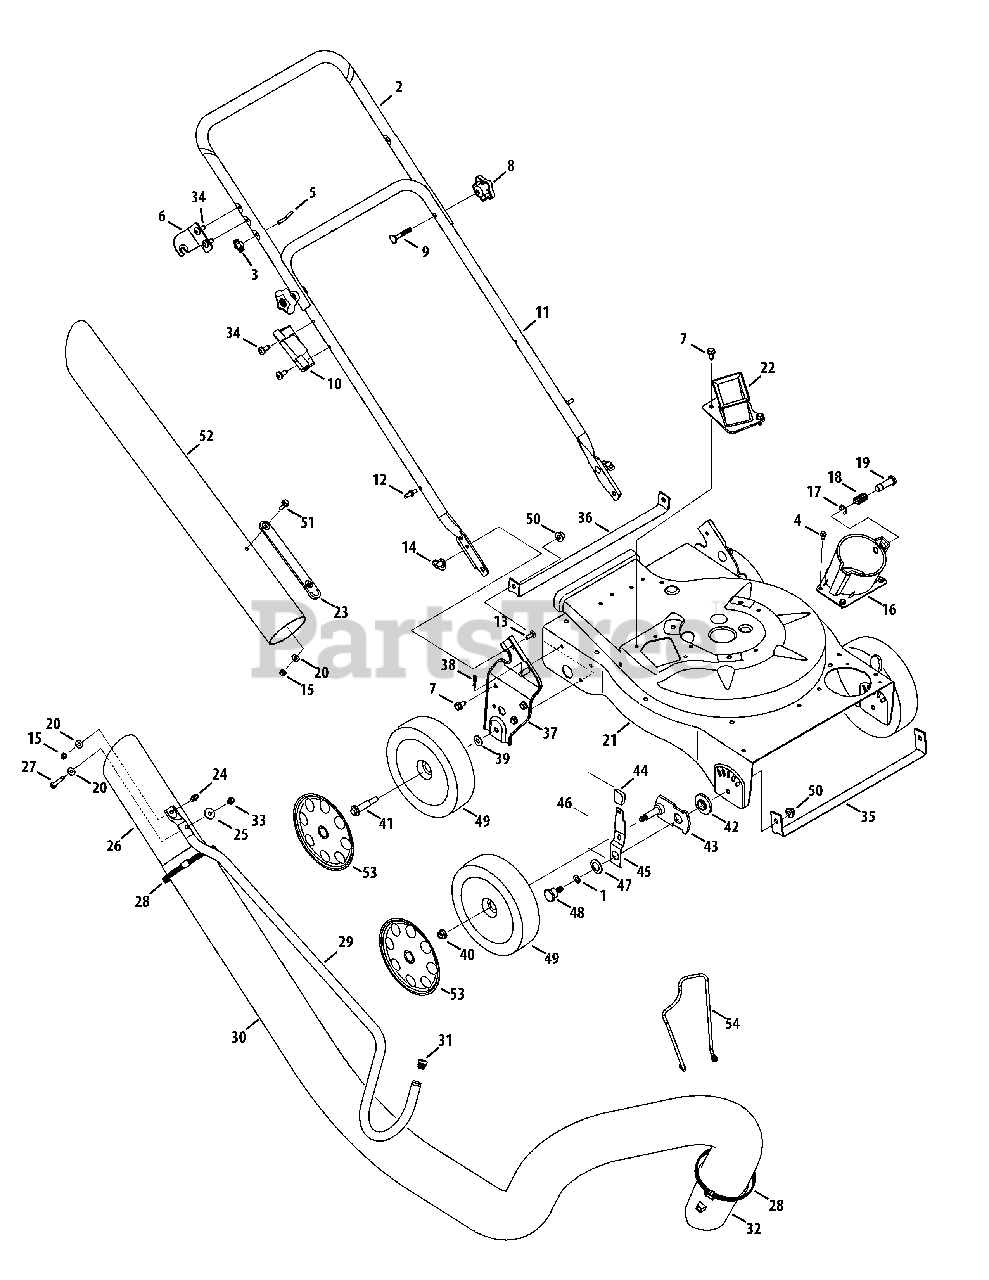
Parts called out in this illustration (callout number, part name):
1	Thrust Washer.375 ID x.70 OD
4	Screw, 1/4-20 x .500
6	Upper Handle Bracket
7	Hex Cap Screw 5/16-12 x.750
9	Carriage Bolt
10	Nozzle Handle Clip
13	Carriage Screw 1/4-20 x.75
14	Wing Nut 1/4-20
15	Hex Lock Nut, 1/4-20
16	Hose Base Adapter Assembly
17	E Ring.500 Dia
18	Compression Spring
19	Clevis Pin
20	Flat Washer.271 ID x.630 OD
21	Upper Flail Housing
22	Chipper Chute Assembly
23	Chute Strap
26	Hose Nozzle
27	Hex Cap Screw 1/4-20 x 2.625
28	Adjustment Clamp
30	Vacuum Hose
31	Handle Plug
32	Hose Adapter, Briggs
32	Hose Adapter, Powermore 173CC
33	Cap Lock Nut, 1/4-20
34	TT Screw, 5/16-18 x .750
35	Front Wheel Support Brace
36	Rear Wheel Support Brace
37	Handle Bracket Ass’y RH
37	Handle Bracket Ass’y LH
38	Cotter Pin
39	Bell Washer.401 ID x.870 OD
40	Flange Lock Nut, 3/8-16
41	Shoulder Screw 3/8-16
42	Height Adjustment Bearing
43	Pivot Arm Assembly
44	Height Adjustment Knob
45	Spring Lever
46	Height Lever Assembly
47	Bell Washer.760 ID x.25 OD
48	Shoulder Screw,.750 x.500
49	Wheel 8 x 2
50	Flange Lock Nut, 3/8-16
51	Screw, 1/4-20 x .75
52	Hose Extension
53	Hubcap, 8"
54	Tube Holder
